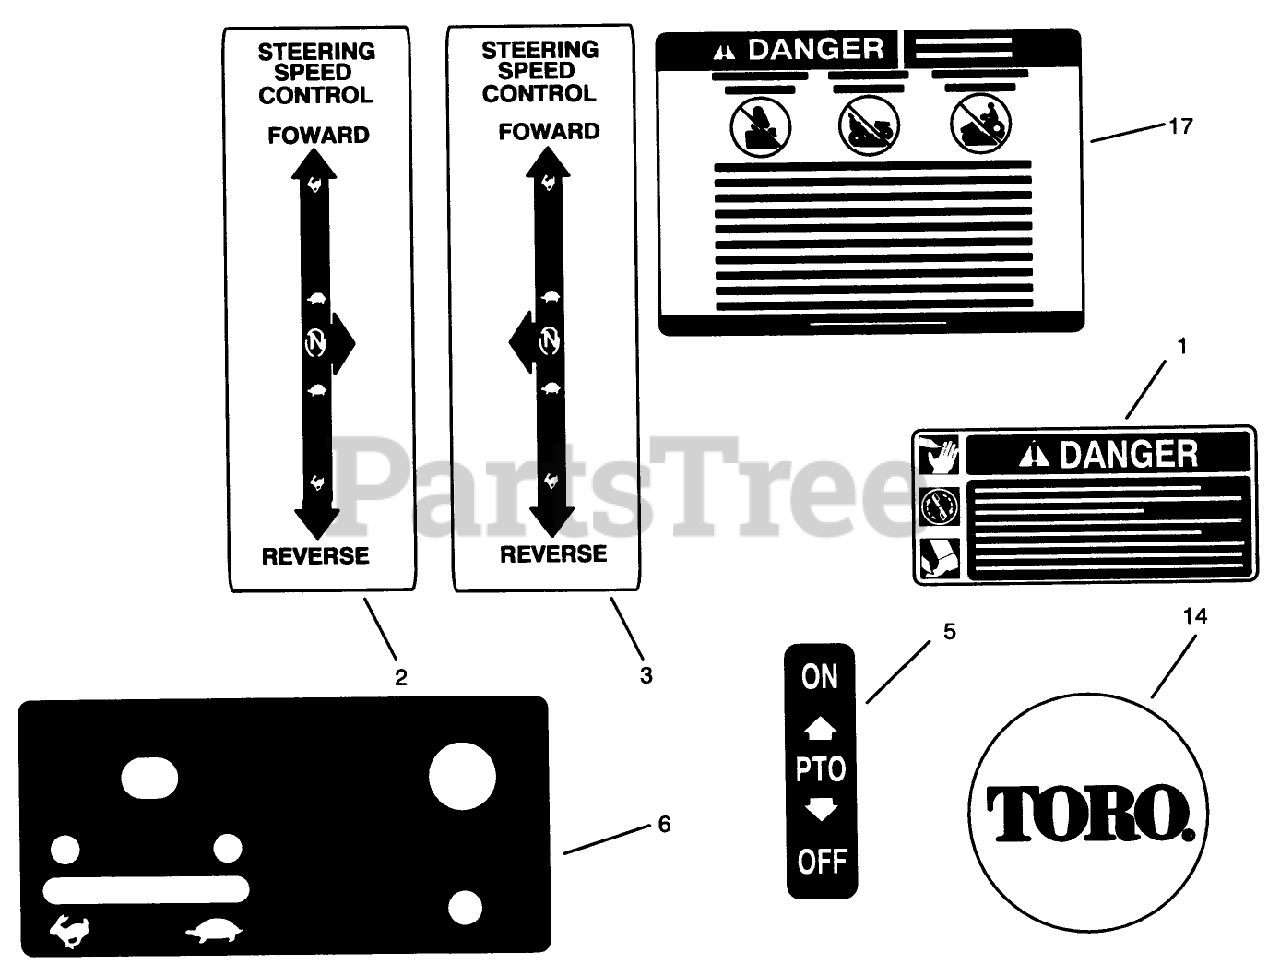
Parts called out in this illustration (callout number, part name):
1	DECAL-DANGER
2	DECAL-LH STRG SPD CONT
3	DECAL-RH STRG SPD CONT
5	DECAL-PTO
6	DECAL-CONTROL
14	NAME-PLATE TORO LOGO
17	DECAL-DANGER
